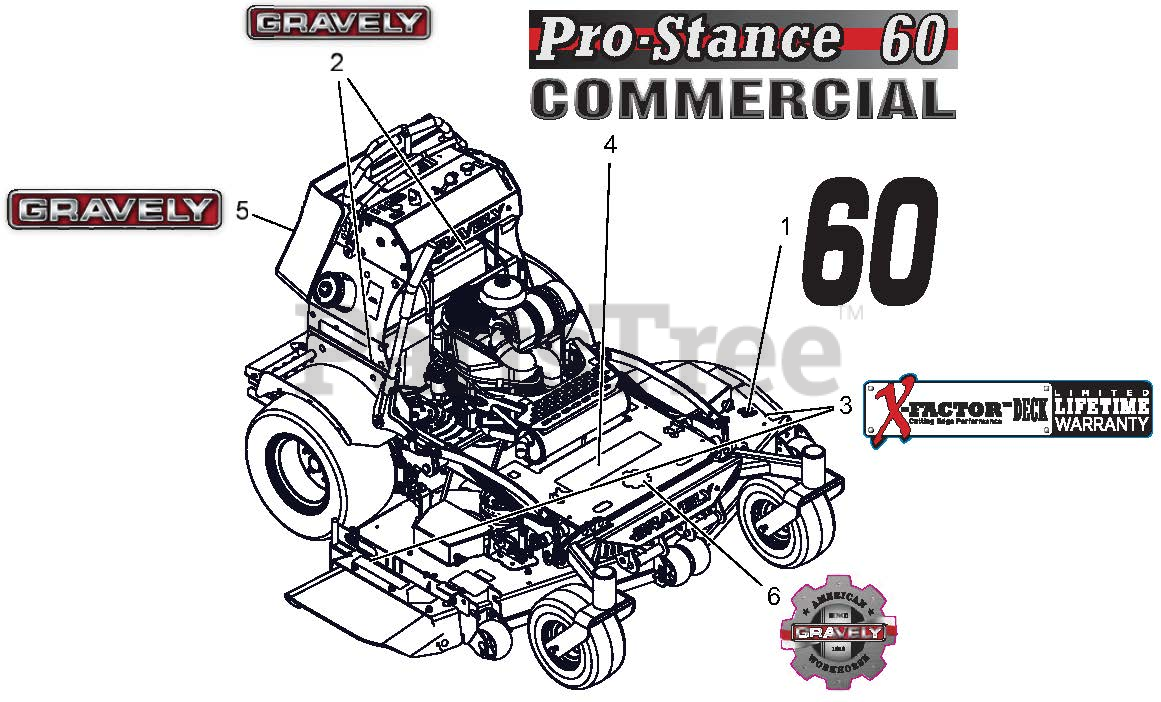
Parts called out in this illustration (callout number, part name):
1	DECAL, 60"
2	DECAL, 9.5" GRAVELY LOGO
3	DECAL, X-FACTOR DECK
4	DECAL, 60" PRO-STANCE SHIELD
5	DECAL, FUEL TANK-GRAVELY
6	DECAL, GRAVELY HERITAGE-LARGE
